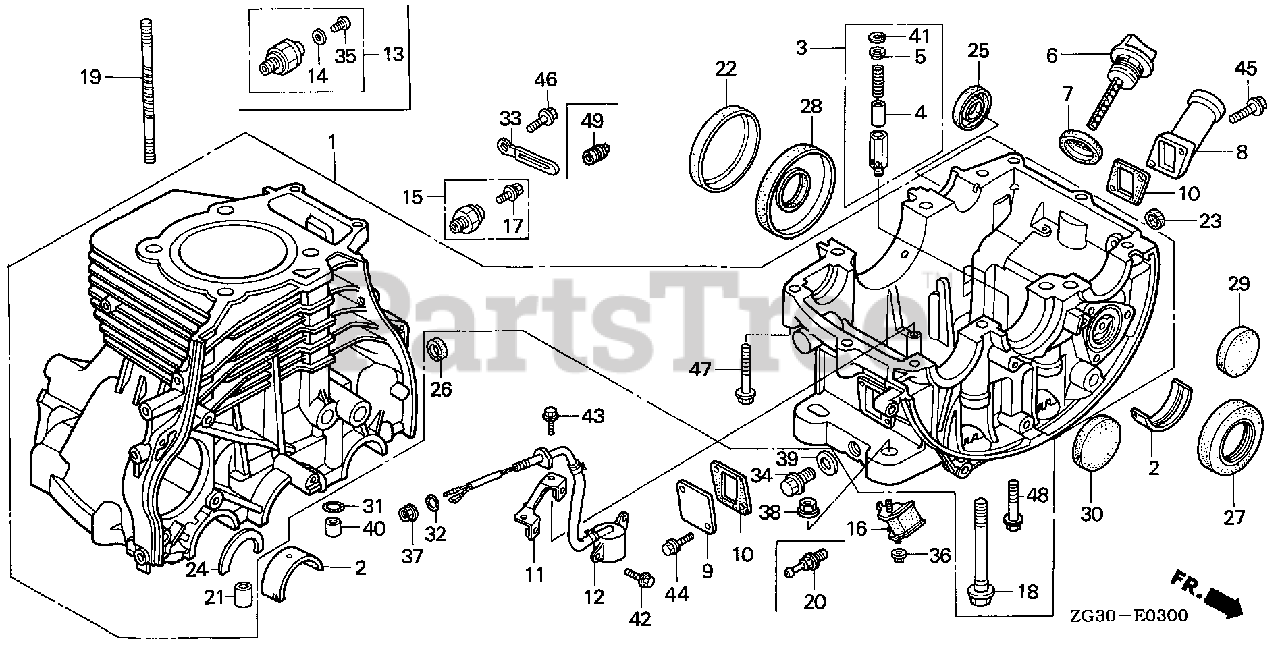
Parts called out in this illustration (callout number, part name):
1	CYLINDER ASSY. (Q-SEL)
2	BEARING A, MAIN (BLUE)
2	BEARING B, MAIN (BLACK)
2	BEARING C, MAIN (BROWN)
2	BEARING D, MAIN (GREEN)
2	BEARING E, MAIN (YELLOW)
2	BEARING F, MAIN (PINK)
2	BEARING G, MAIN (RED)
2	BEARING A, MAIN (UNDER SIZE 0.25) (BLACK)
2	BEARING B, MAIN (UNDER SIZE 0.25) (BROWN)
2	BEARING C, MAIN (UNDER SIZE 0.25) (GREEN)
2	BEARING A, MAIN (UNDER SIZE 0.50) (BLACK)
2	BEARING B, MAIN (UNDER SIZE 0.50) (BROWN)
2	BEARING C, MAIN (UNDER SIZE 0.50) (GREEN)
2	BEARING A, MAIN (UNDER SIZE 0.75) (BLACK)
2	BEARING B, MAIN (UNDER SIZE 0.75) (BROWN)
2	BEARING C, MAIN (UNDER SIZE 0.75) (GREEN)
3	VALVE ASSY., RELIEF (NOT AVAILABLE)
4	VALVE, RELIEF
5	SEAT, RELIEF VALVE (NOT AVAILABLE)
6	CAP, OIL FILLER
7	GASKET, OIL FILLER CAP
8	EXTENSION, OIL FILLER
9	PLATE, EXTENSION
10	GASKET, EXTENSION OIL FILLER (NON-ASBESTOS)
18	BOLT-WASHER (11X115)
19	BOLT, STUD (10X103.5)
21	PIN, DOWEL (13X20)
23	OIL SEAL (8X14X5)
26	OIL SEAL (8X14X5)
27	OIL SEAL (40X67X10)
28	OIL SEAL (36X90X9)
29	PLUG, SEALING (47MM)
30	PLUG, SEALING (52MM)
31	O-RING (9.8X1.9)
34	BOLT, DRAIN PLUG (14MM)
39	WASHER, DRAIN PLUG (14MM)
40	PIN, DOWEL (10X16)
41	CIRCLIP (INNER) (12MM)
44	BOLT, FLANGE (6X16)
45	BOLT, FLANGE (6X22)
48	BOLT, FLANGE (8X40)
48	BOLT, FLANGE (8X50)
